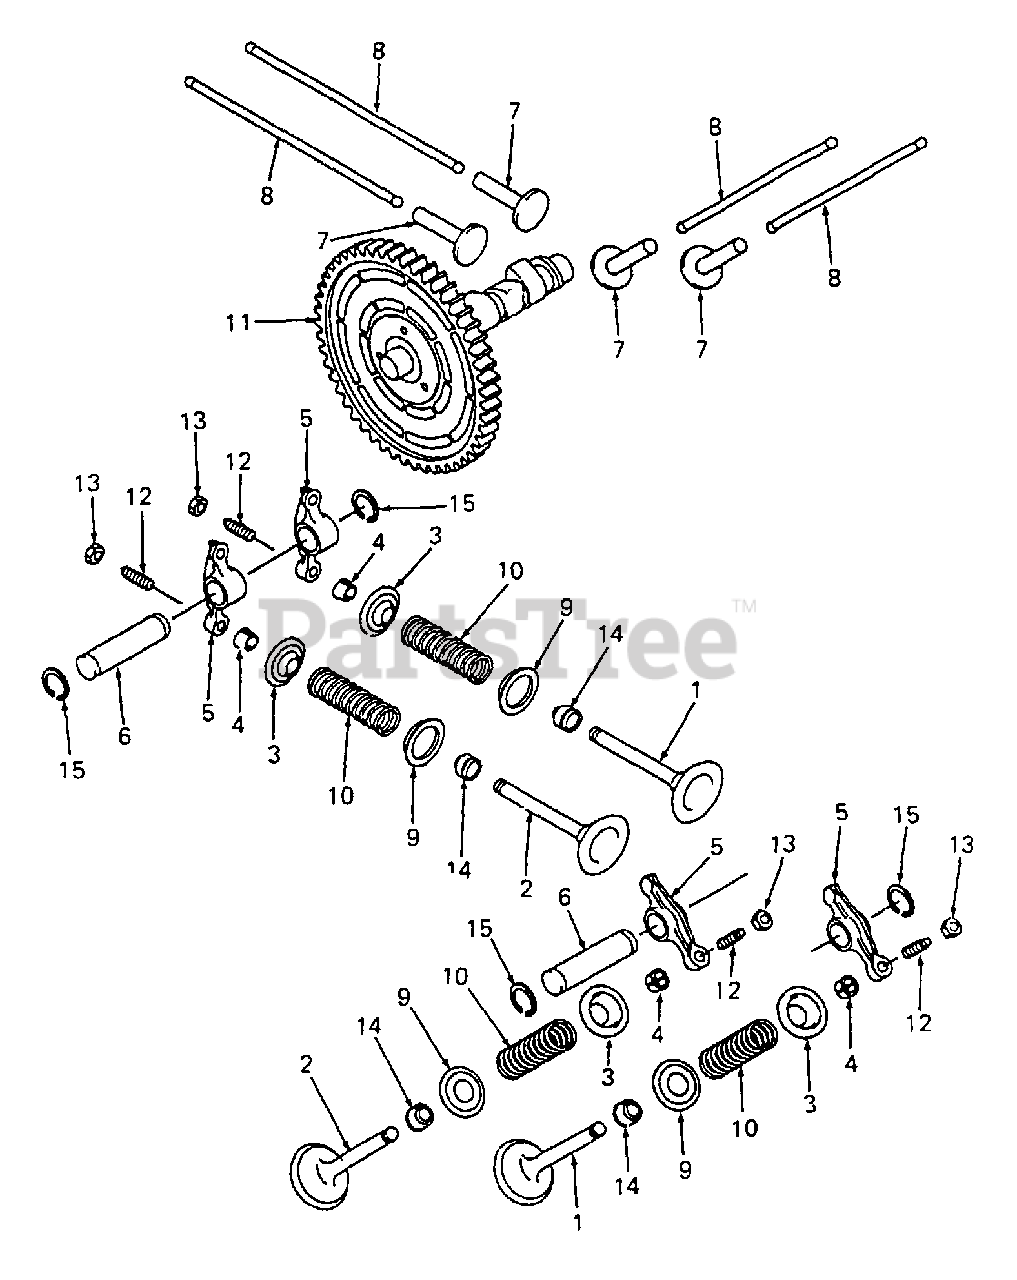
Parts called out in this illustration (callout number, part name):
1	Valve, Intake
2	Valve, Exhaust
3	Retainer, Valve Spring
6	Shaft, Rocker
9	Retainer, Spring
10	Spring, Valve
11	Camshaft Assy
12	Screw, Valve Adjust
13	Nut, Valve Adjust Lock
15	Circlip, 12 MM
